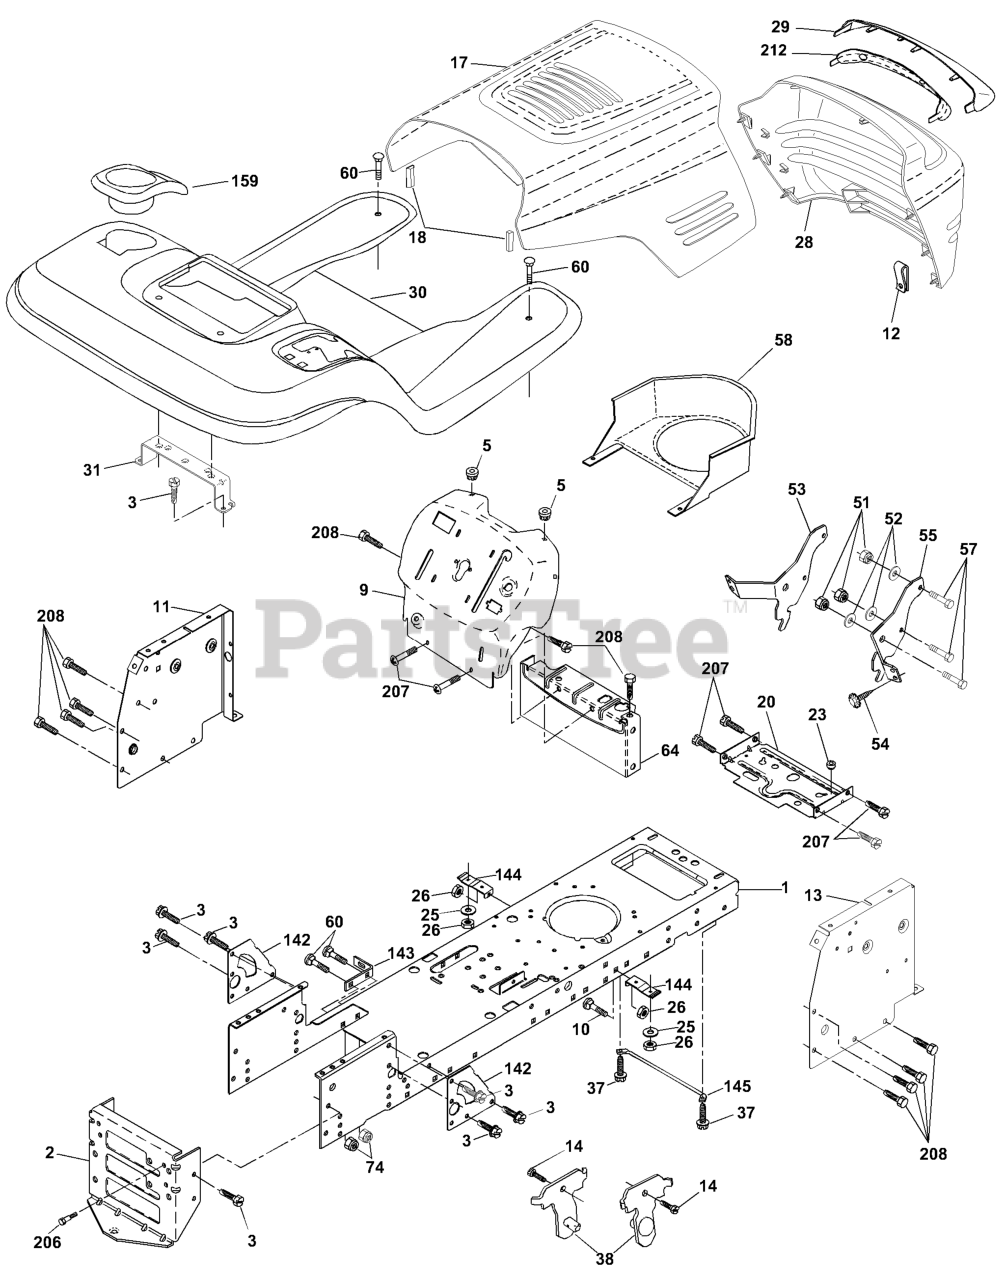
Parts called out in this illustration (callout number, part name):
1	CHASSIS STAMPING
2	DRAWBAR, 12GA
3	SCREW 3/8-16X3/4
5	BUMPER.RUBBER.HOOD
9	DASH SLKSCR
10	BOLT D
11	PANEL DASH LH
13	PANEL ASM, DASH RH
14	SCREW LT
17	HOOD ASM.
18	BUMPER HOOD T
20	PLATE MTG
23	BUSHING.SNAP.NYL.BLK.
25	WASHER
26	NUT
28	GRILLE ASM
29	LENS
30	FENDER FOOTREST STLT PNT
31	BRACKET.SUPPORT.FENDER
37	Screw Thdrol 5/16-18 x 1/2
38	BRACKET.ASM.PIVOT.MOWER.REAR
51	LOCKNUT.NYLOC.1/4-20
52	WASHER
53	BRACKET.GRILLE.LH
54	SCREW.HEX.WS.HD.8-18 X 7/8
57	BOLT
58	AIR CONDUCTOR
60	Bolt RDHD SQNK 3/8-16 x 3/4
64	DASH LOWER
142	PLATE
143	BRACKET, SWAY BAR
144	BRKT, FOOT REST
145	ROD PIVOT CHASSIS/HOOD
159	CUPHOLDER
206	SHOULDER BOLT 5/16-18TT
207	SCREW, 5/16-18 X 1/2
208	SCREW 3/8-16X1/2
212	REPL BY 532 1745-03
